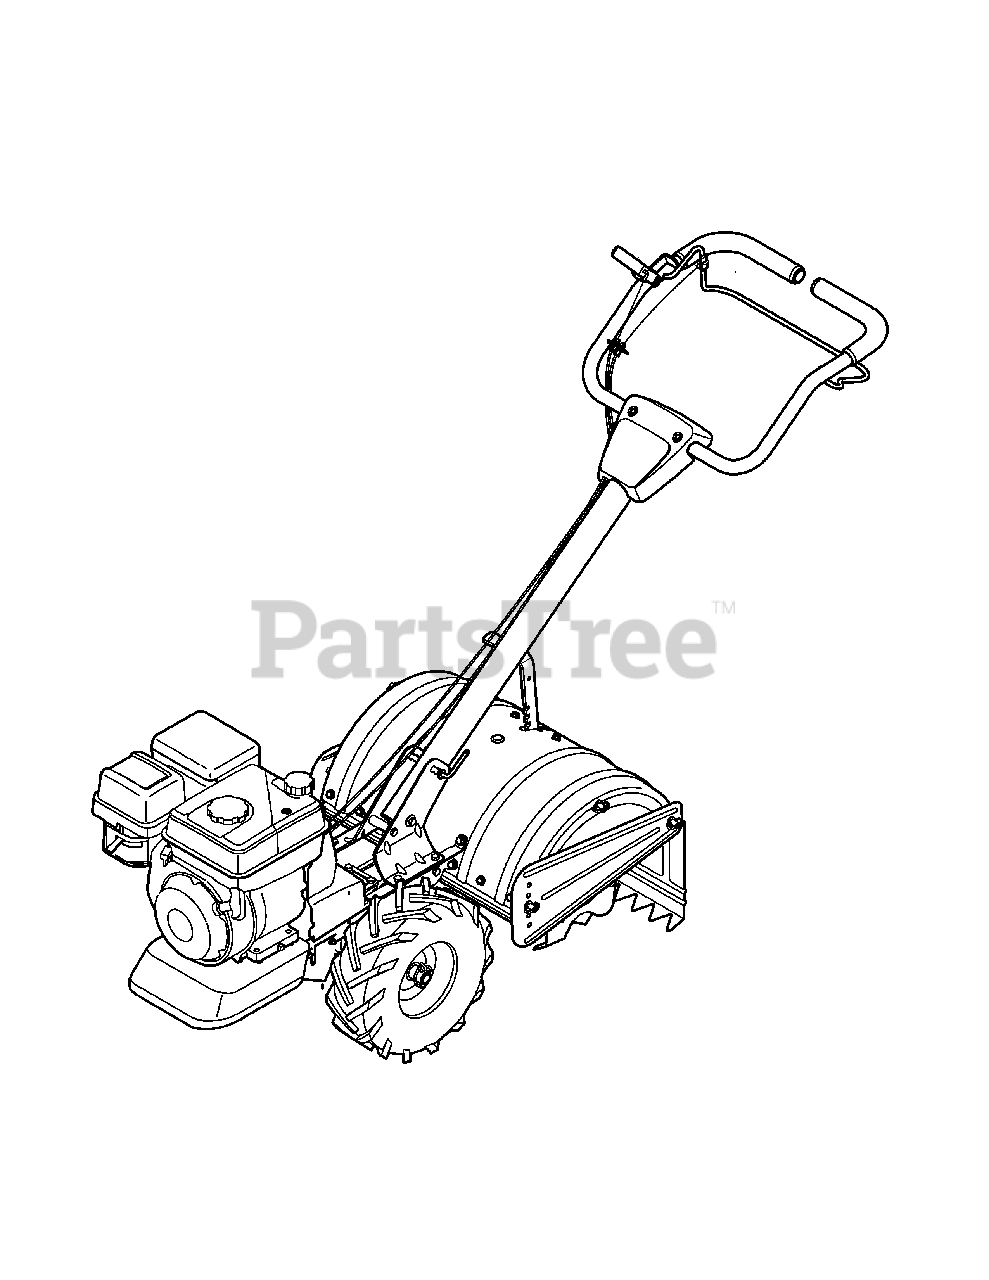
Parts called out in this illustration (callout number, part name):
NA	Pre Filter
NA	Tines-Inner (LH)
NA	Tines-Inner (RH)
NA	Rim
NA	Tire
NA	Foam Grip
NA	Handle Knob
